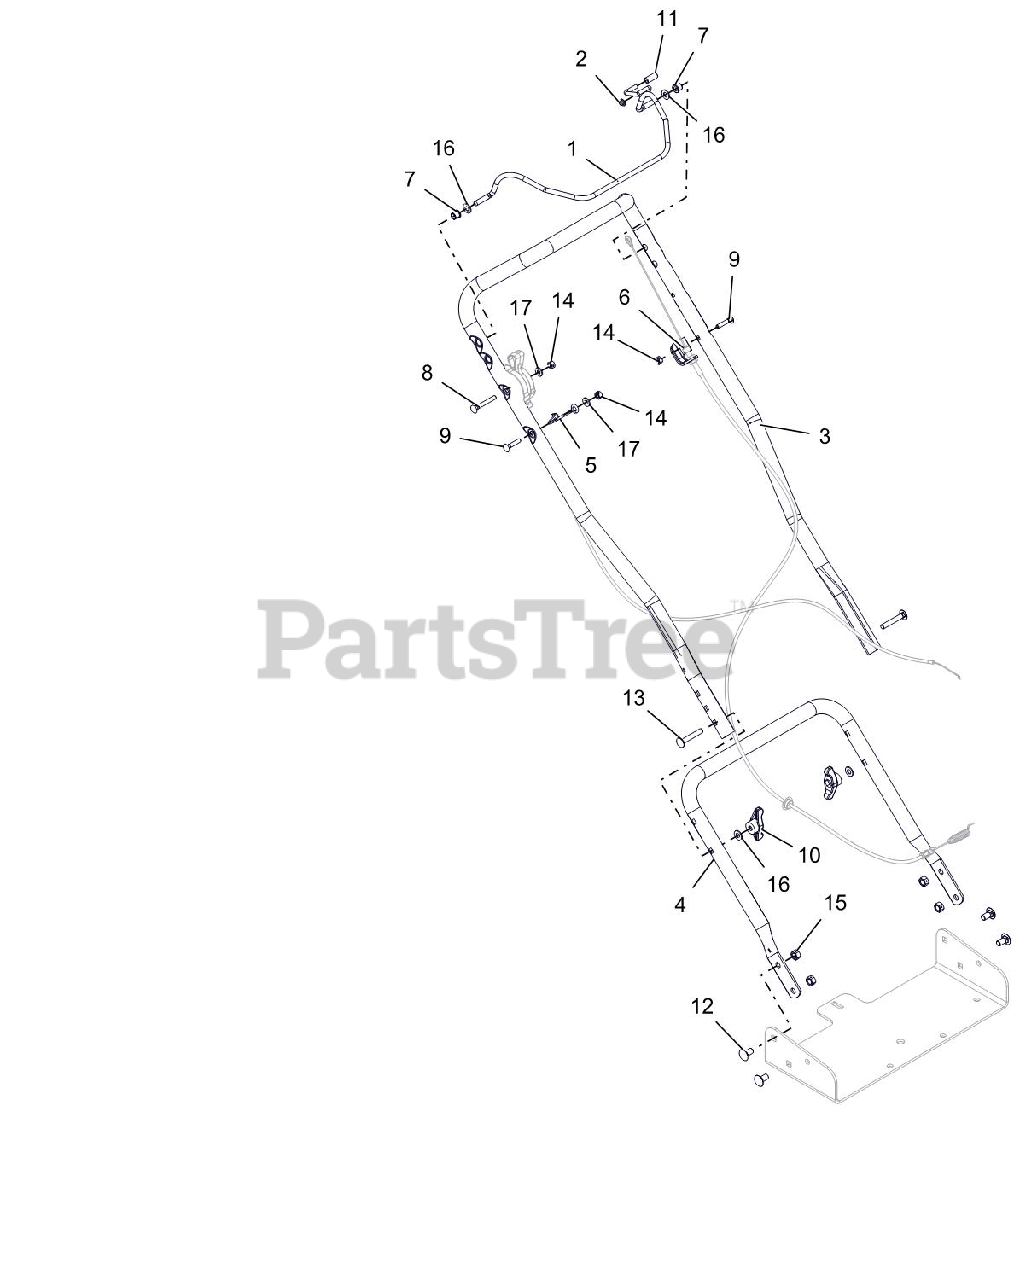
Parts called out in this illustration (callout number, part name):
1	BAIL SS LF
2	PUSH NUT, .25
3	HANDLEBAR - UPPER
4	HANDLEBAR - LOWER
5	GUIDE - PULLCORD
6	ANCHOR - CABLE
7	BSHG-FLG .325X.444X.440X.560
8	BLT-RDHDXLSQNK .25-20X2.0 G5YZ
9	BLT-RDHDXLSQNK.25-20X1.25 G5ZC
10	KNOB,WING .31-18 UNC NYL/TALC
11	CAP, VINYL, .25 ID
12	@BLT-RDHDSQNK .38-16X.75 G5YZ
13	BLT-RDHDSQNKFT .31-18X2.0 G5YZ
14	@NUT-LK-CTR .25-20 YWZC
15	@NUT-LK-CTR .38-16 YWZC
16	@WSHR-FL-STL.344X.688X.065YWZC
17	@WSHR-FL-STL.281X.62X.065 YWZC
